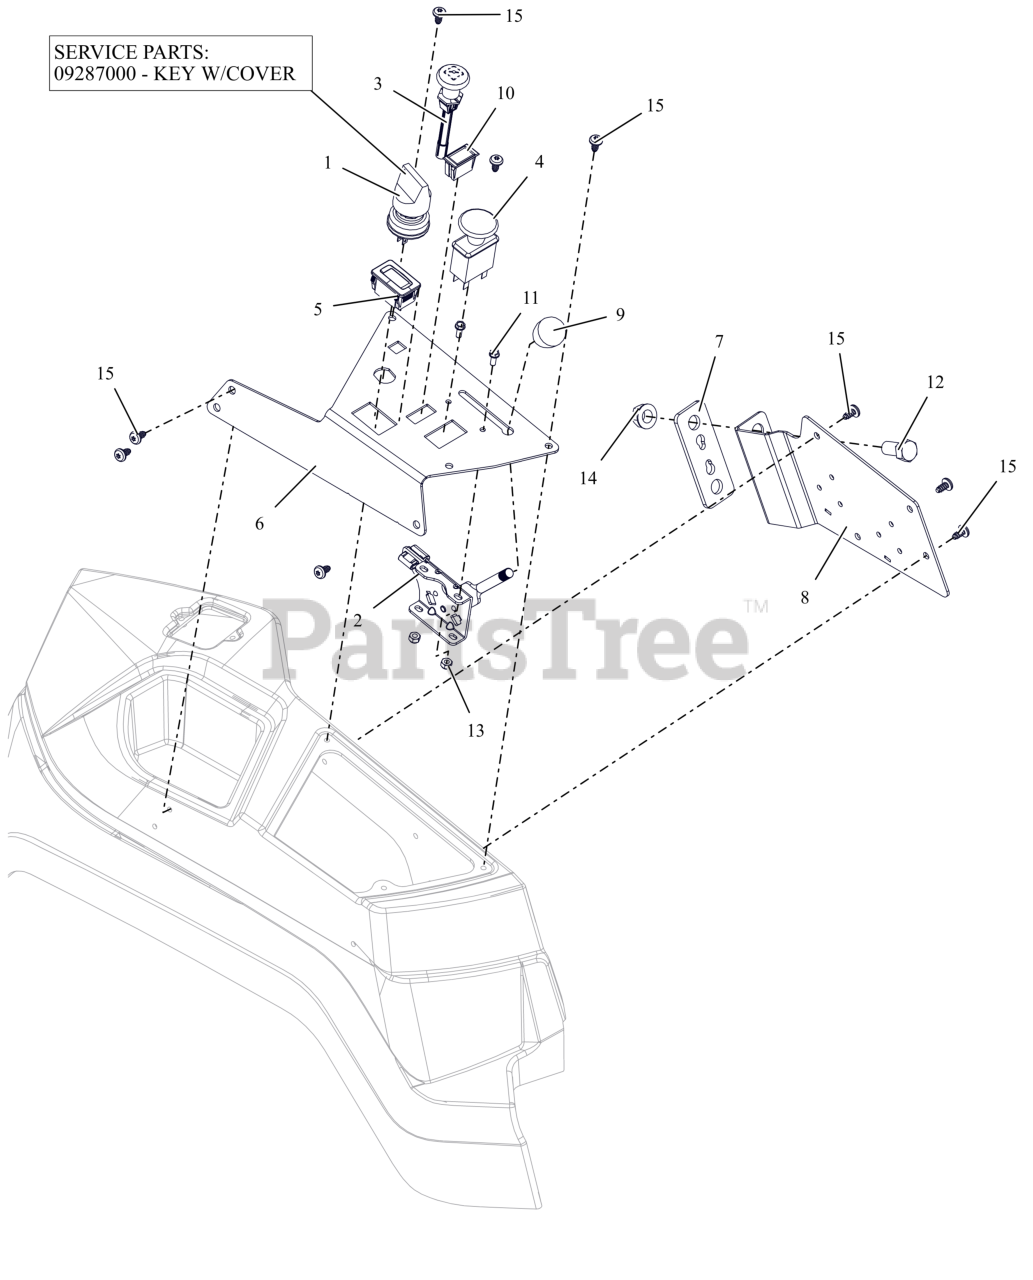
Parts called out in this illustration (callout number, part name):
1	SWITCH, IGNITION
1	KEY, W/ SHIELD
2	CABLE, PRO THROTTLE CONTROL
3	CABLE - CHOKE, SNAP-IN
4	SWITCH, CLUTCH
5	HOUR METER
6	PLATE, APEX CONTROL PANEL
7	PLATE, CONTROL PANEL SPACER
8	BRKT, FENDER/RELAY MOUNTING
9	KNOB-CONTROL-BLACK .38-16X.50
10	SWITCH,BLANK
11	BLT, HWH #10-24X.50 ZCC
12	BLT, HEX .50-13X1.00 G5 ZCC
13	NUT-LK-NYL #10-24 G2 ZCC
14	NUT-LK-TOP-FLG .500-13 GF ZCC
15	SCR-PAN .25-15X.50 6L H/LZB500
